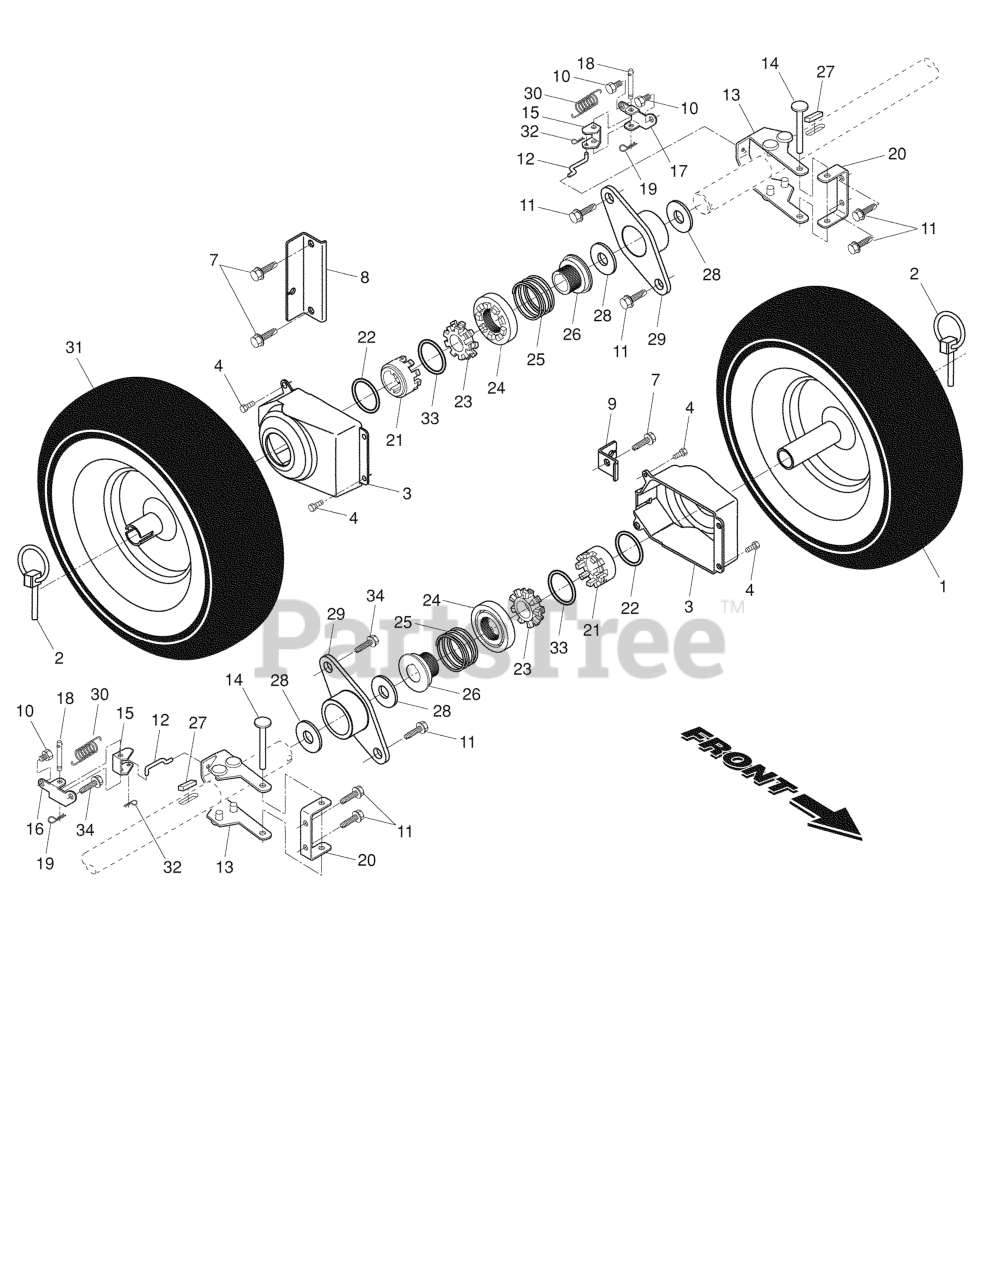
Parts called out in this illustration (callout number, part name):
1	16 X 4.8 LH WHEEL GREY
2	PIN KLIK, 1/4
3	COVER, POWER STEERING
4	SCREW, HEX HEAD, TAPPING
7	Capscrew, Hex Head, Flanged 3/8-16 x 1
8	BRACKET, STEERING CABLE RH
9	BRACKET, STEERING CABLE LH
10	SCREW 1/4X20
11	Screw, Hex Head 5/16-18 x 1/2
12	LINK.STEER.YOKE
13	YOKE, STEERING
14	PIN, STEERING LEVER
15	BELLCRANK.STEER
16	BRACKET.STEER.PIVOT.LH.YZ
17	BRKT.STEER.PIVOT.RH
18	PIN, STEERING BELLCRANK
19	RETAINER CLIP PM
20	BRACKET.STEER.PNT.BLACK
21	RP.DRIVER WHEEL
22	RING, WIRE RETAINER
23	LOBE WHEEL
24	RP.SLIDE.CLUTCH
25	SPRING, CLUTCH SLIDE
26	RP.LOBE.AXLE
27	KEY, SQUARE 1/4 X .875
28	WASHER TRUST 1"
29	BEARING, AXLE
30	SPRING LATCH
31	16 X 4.8 RH WHEEL
32	RETAINER CLIP
